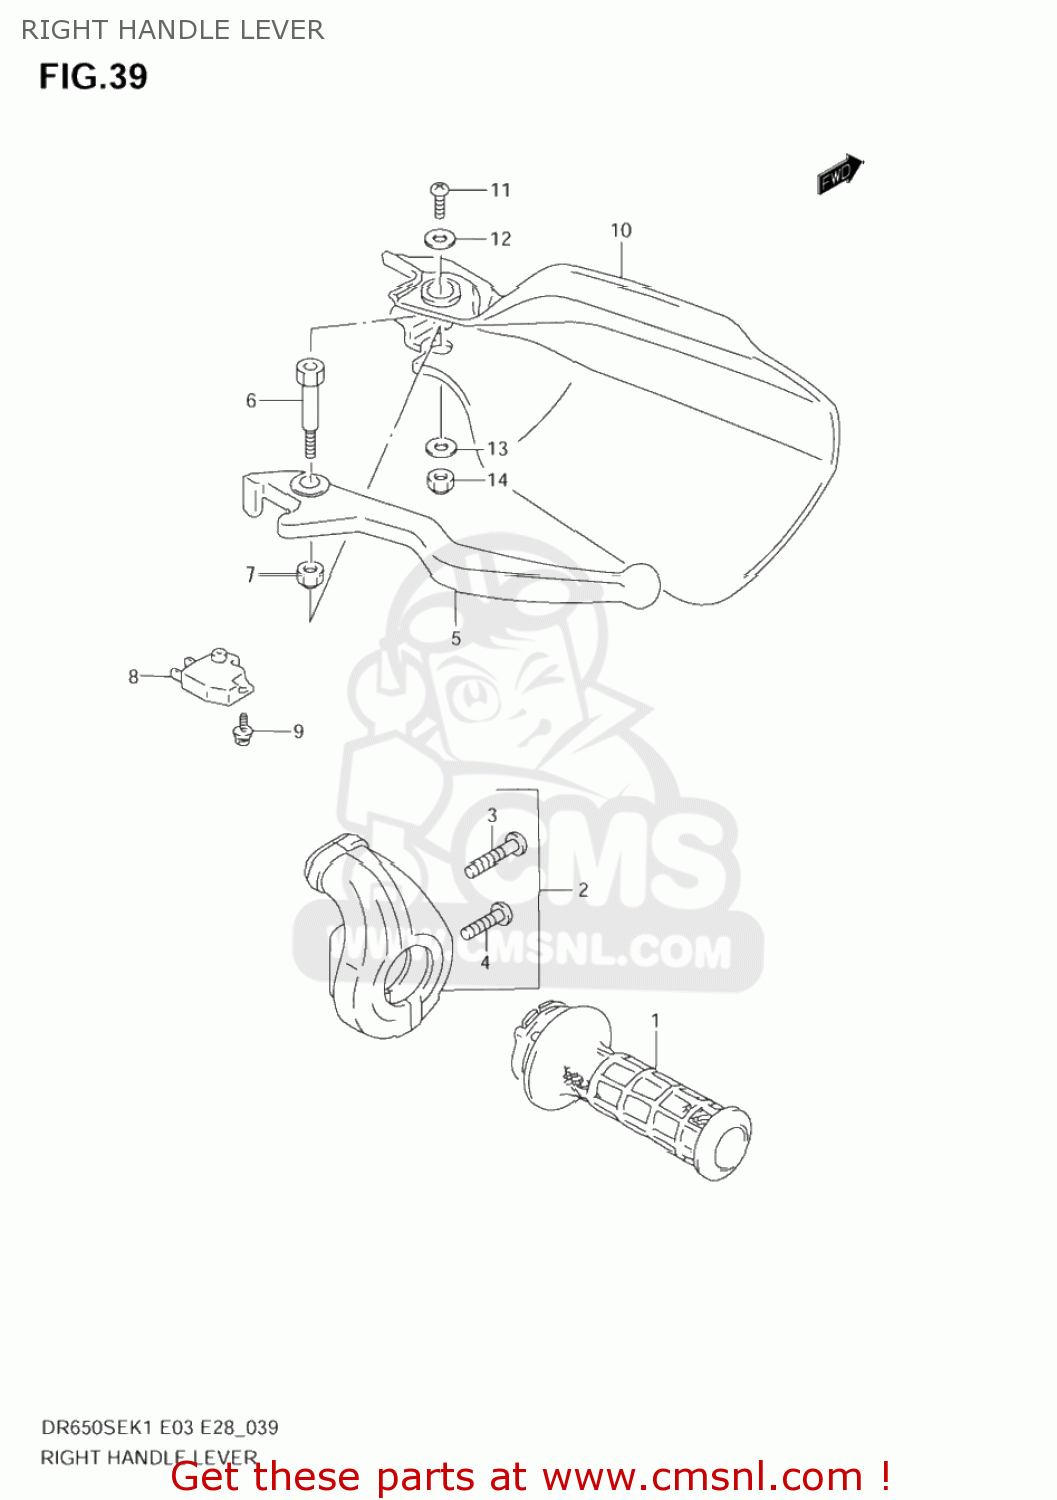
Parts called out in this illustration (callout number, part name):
1	GRIP,THROTTLE
2	CASE ASSY,THROTTLE
3	SCREW(5X25)
4	SCREW
5	LEVER,BRAKE
6	BOLT,BRAKE LEVER PIVOT
7	NUT,LEVER PIVOT
8	SWITCH ASSY,ST
9	SCREW
10	COVER,KNUCKLE,RIGHT
11	SCREW
12	WASHER(5.5X16X1.2)
13	WASHER(6.5X16X1.6)
14	NUT 6MM
